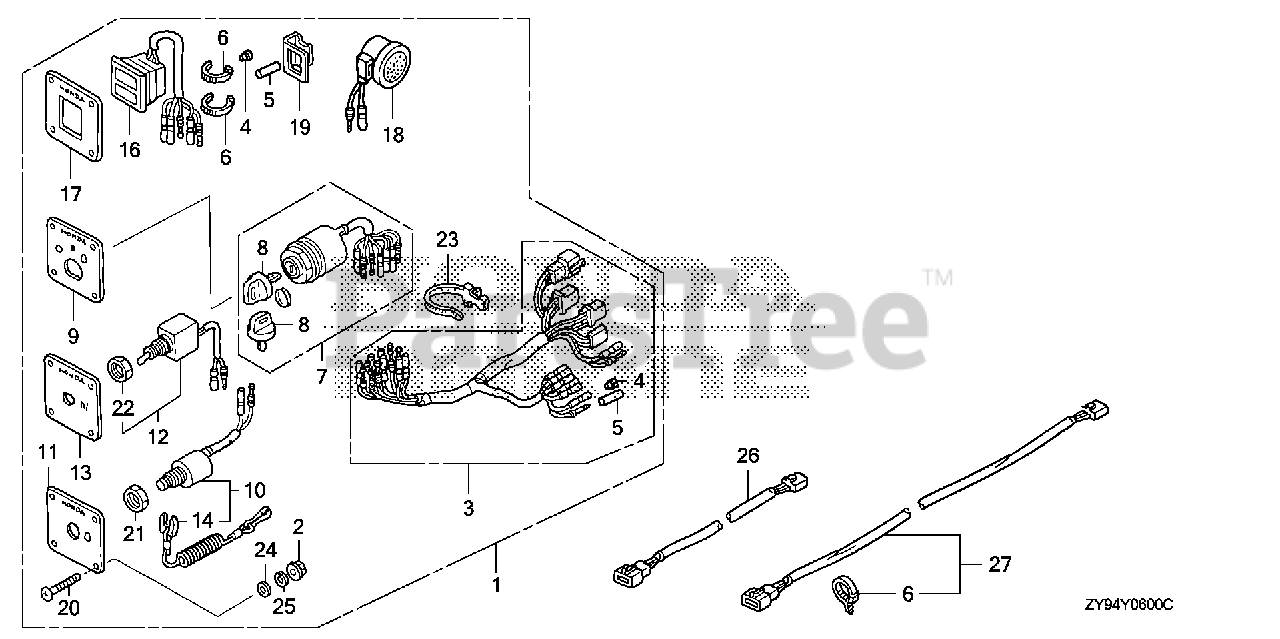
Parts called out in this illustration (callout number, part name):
1	PANEL KIT, CONTROL (2-LED) (A)
2	NUT, FLANGE (5MM) DUAL QTY = (8) (SINGLE)
3	HARNESS ASSY., SWITCH PANEL
4	PLUG, CONNECTOR (INNER) (TROLLING CONTROL)
5	PLUG, CONNECTOR (OUTER) (ENGINE NO.)
6	TIE, CABLE (NATURAL 2.4X92) Use up to Frame SN 1300359.
7	SWITCH ASSY., COMBINATION DUAL QTY = (2) (SINGLE)
7	SWITCH ASSY., COMBINATION (SINGLE) (DUAL)
8	KEY ASSY., COMBINATION SWITCH (35100-ZV5-003 ONLY) DUAL QTY = (4) (SINGLE)
9	PANEL, SWITCH
10	SWITCH ASSY., EMERGENCY STOP
11	PANEL, EMERGENCY STOP SWITCH
12	SWITCH ASSY., SOLENOID
13	PANEL, SOLENOID
14	WIRE, EMERGENCY (SINGLE) (DUAL)
16	LAMP ASSY., INDICATOR (2-LED)
17	PANEL, INDICATOR
18	BUZZER, WARNING
19	BRACKET, BUZZER
20	SCREW, PAN (5X40) DUAL QTY = (8) (SINGLE)
21	NUT, HEX. (16MM) DUAL QTY = (2) (SINGLE)
22	NUT, HEX. (12MM)
23	BAND, WIRE HARNESS (150MM) (NATURAL) DUAL QTY = (2) (SINGLE)
24	WASHER, PLAIN (5MM) DUAL QTY = (8) (SINGLE)
25	WASHER, SPRING (5MM) DUAL QTY = (8) (SINGLE)
26	CABLE ASSY., EXTENSION (3P 7FT) (FOR 2-LED)
27	CABLE ASSY., EXTENSION (3P 30FT) (FOR 2-LED)
